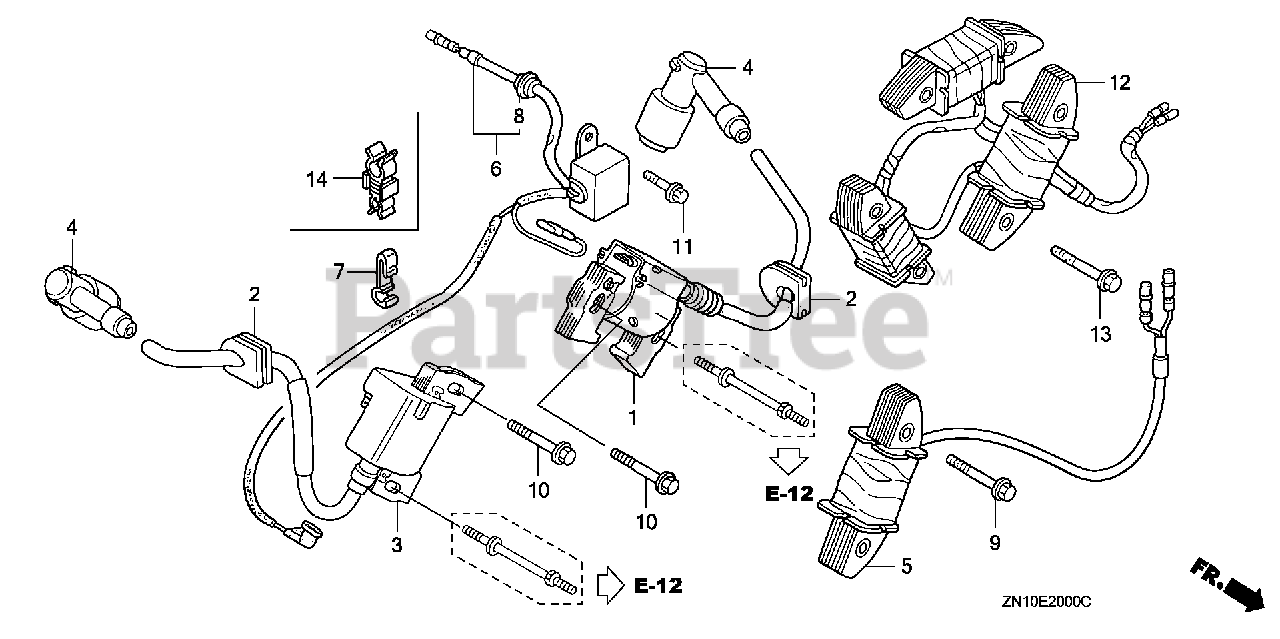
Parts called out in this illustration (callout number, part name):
1	COIL ASSY., IGNITION (200MM) (BLACK)
2	GROMMET, IGNITION WIRE
3	COIL ASSY., IGNITION (215MM) (GRAY)
4	CAP ASSY., NOISE SUPPRESSOR
5	COIL ASSY., CHARGE (12V/3A)
6	DIODE ASSY., ENGINE STOP
8	GROMMET, TOOL
9	BOLT, FLANGE (6X35) (CT200)
10	BOLT, FLANGE (6X32) (CT200)
11	BOLT, FLANGE (6X8)
